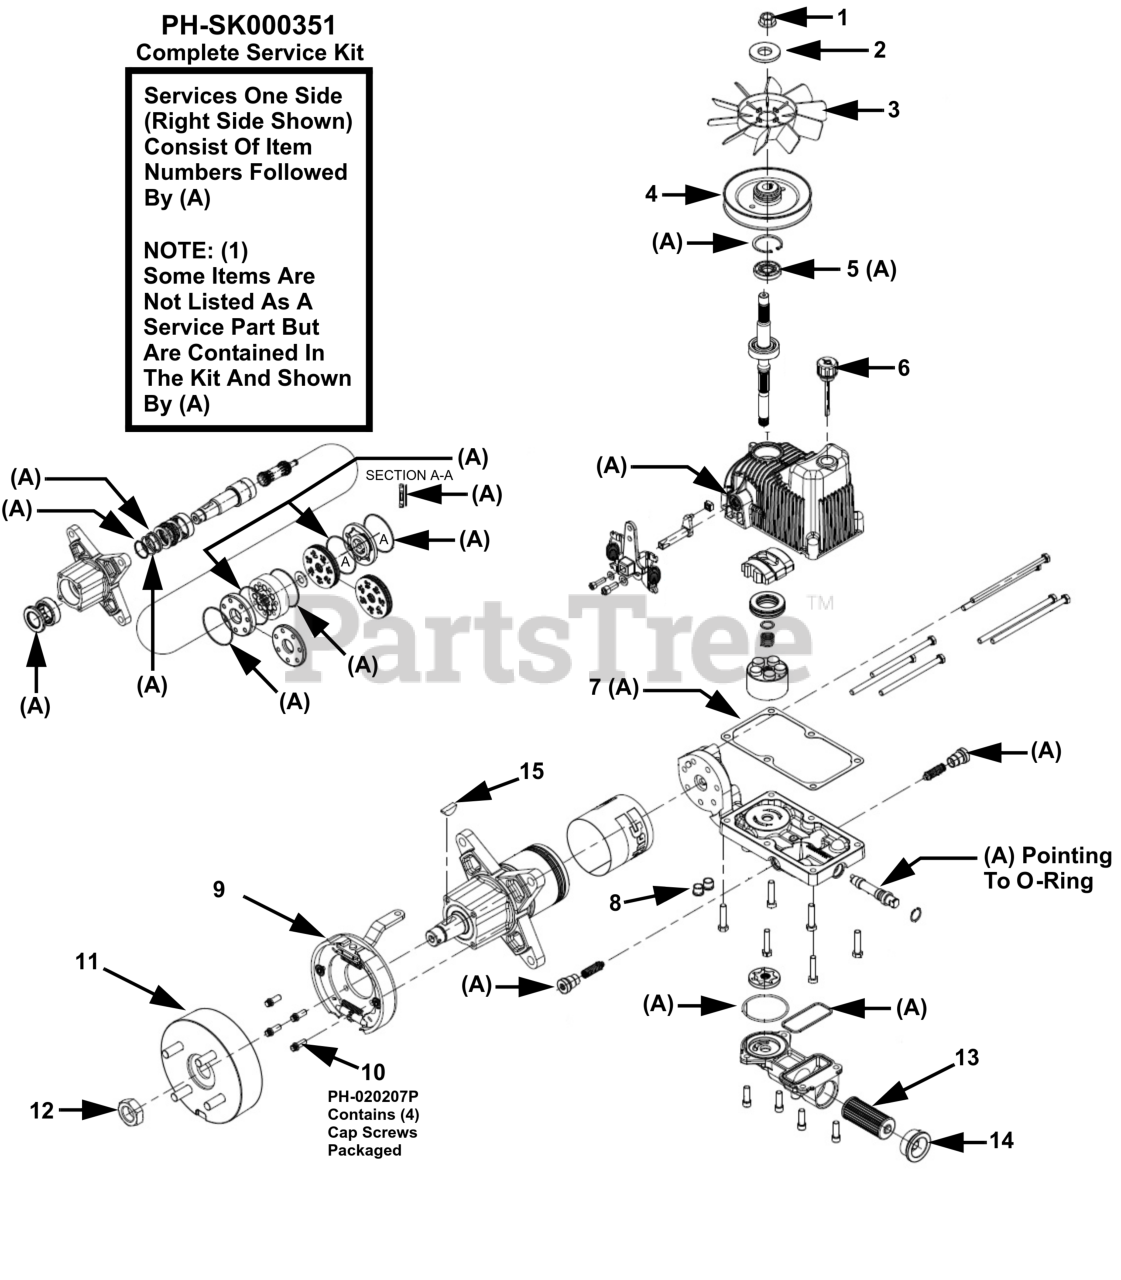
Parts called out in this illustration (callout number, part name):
1	NUT-FLANGE 1/2-20
2	SPACER-FAN
6	BREATHER
8	PLUG-MAGNETIC HEX
9	BRAKE ASSEMBLY-ON HOLE LEVER
10	SCREW-CAP (QTY 4)
11	DRUM-4 BOLT BRAKE
12	NUT-SLOTTED
14	PLUG & O-RING ASSE
15	WOODRUFF KEY
420112	RETURN SERVICE KIT
A	COMPLETE SEAL SERVICE KIT
